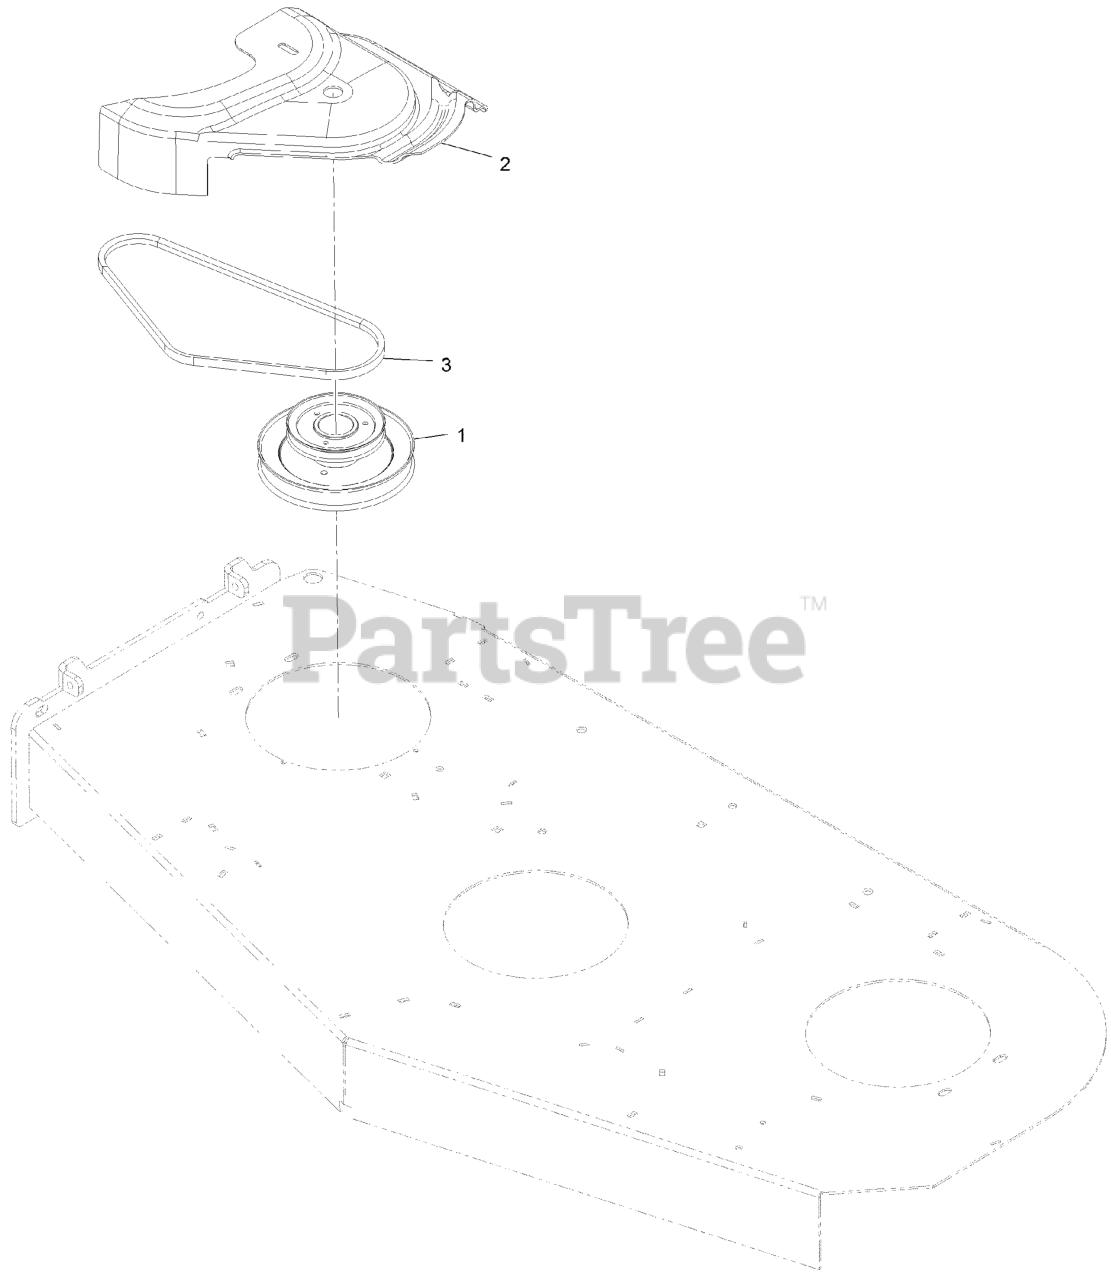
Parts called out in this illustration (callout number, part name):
1	JACKSHAFT,UV DRIVE 604 SPLINED
2	COVER,BELT DUV 60
3	BELT, BLOWER DRIVE 60
